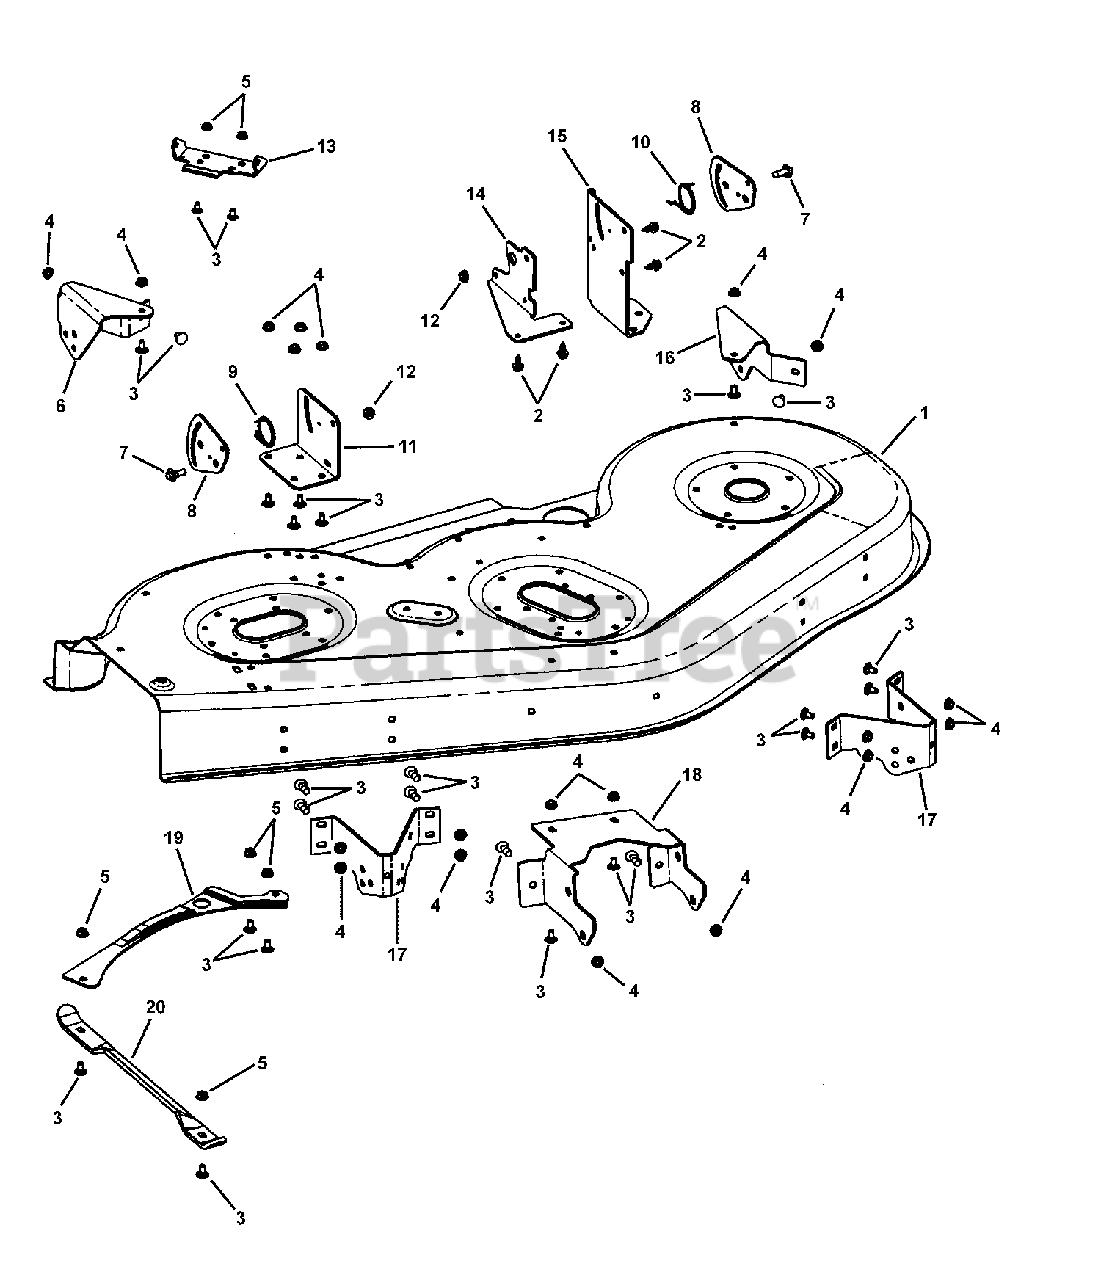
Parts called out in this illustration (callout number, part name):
1	HOUSING, 52" Mower Deck
2	CAPSCREW, 5/16-18 Hex Washer Face
3	BOLT, 5/16-18 x 5/8" Square Neck Carriage, GR 5
4	NUT, 5/16-18 Hex Flange Ser YZ
5	NUT, 5/16-18 Hex Flange Lock, NC
6	BRACKET, Gage Wheel RH Rear
7	BOLT, 3/8-16 Shoulder
8	PLATE, Suspension
9	SPRING, Torsion RH
10	SPRING, Torsion LH
11	BRACKET, Lifter RH
12	NUT, 3/8-16 Hex Flange Lock, NC
13	BRACKET, Hinge
14	BRACE, LH Lifter
15	BRACKET, Lifter LH
16	BRACKET, Gage Wheel LH Rear
17	BRACKET, Gage Wheel 52 Deck
18	BRACKET, Front Deck
19	BAFFLE, RH Bottom
20	BRACKET, Chute Support
